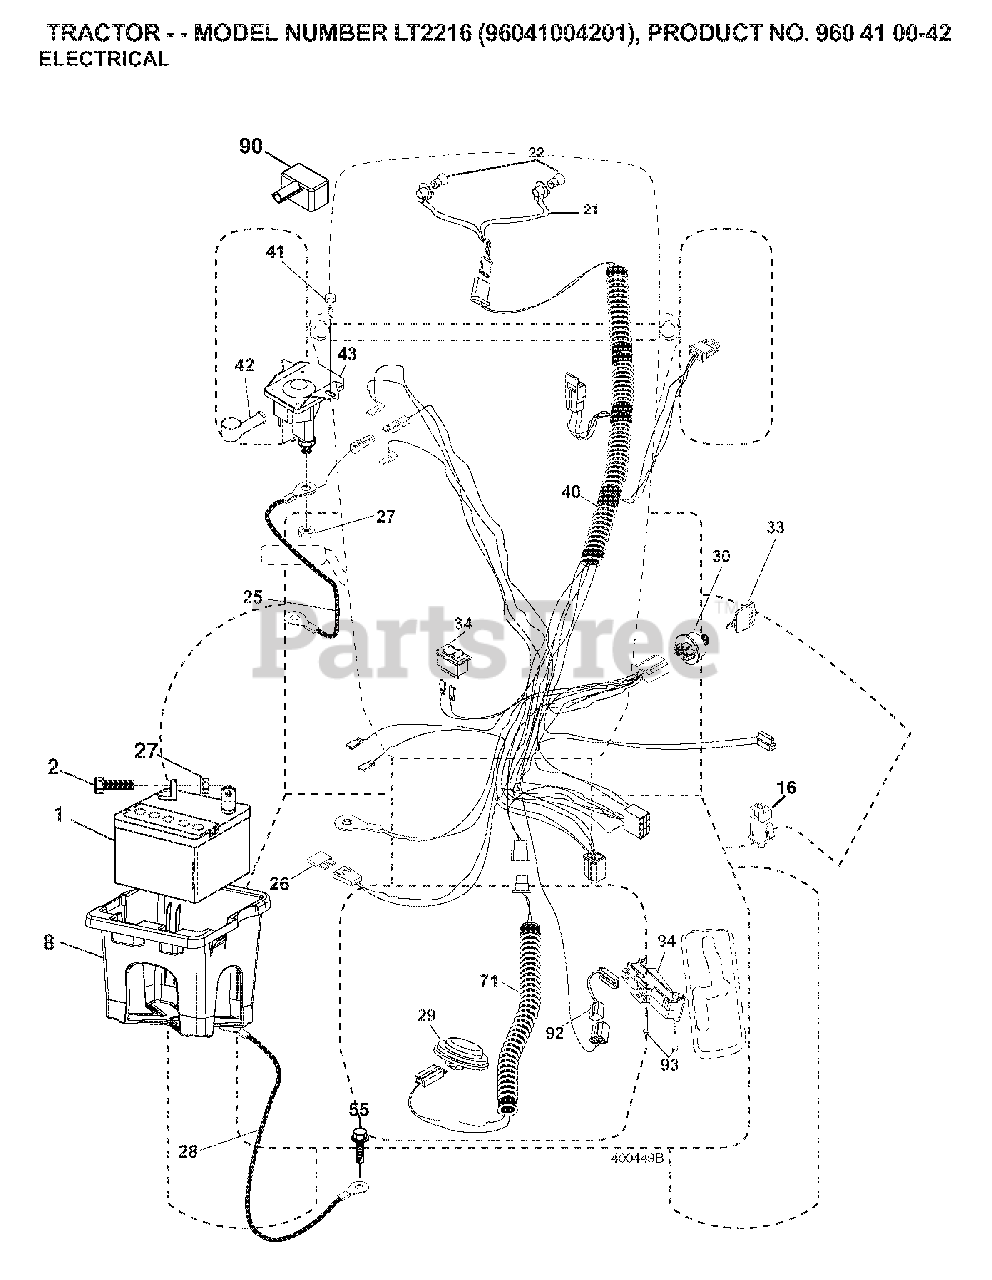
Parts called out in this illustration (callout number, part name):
1	BATTERY 12V .35 AMP
8	BOX.BATTERY.MNT.REAR.L
16	SWITCH INTERLOOK PUSH-IN
21	HARNESS ASSY LIGHT
22	LIGHTBULB
25	CABLE.STARTER.6GA.RED.
26	FUSE 20AMP
27	NUT
28	CABLE.BLACK.18"REAR.BA
29	SWITCH.SEAT.DELTA.OPC.
30	SWITCH.IGN.DELTA.W.LGH.ROS
33	KEY MLD GEN DELTA
34	SWITCH LT
40	HARNESS.IGN.CHASS.TEX.REAR.BAT
41	SCREW
42	TERMINAL COVER
43	SOLENOID.W/BRASS.PLUNG
55	SCREW 5/16"
71	HARNESS IGN. DASH
79	BULB HOLDER ASM.
87	SWITCH.INTRLCK.CLUTCH.
90	COVER, TERMINAL BATTERY
92	HARNESS.PIGTAIL.CONSLE
93	SCREW.PLASTITE
94	MODULE.REVERSE.ROS
